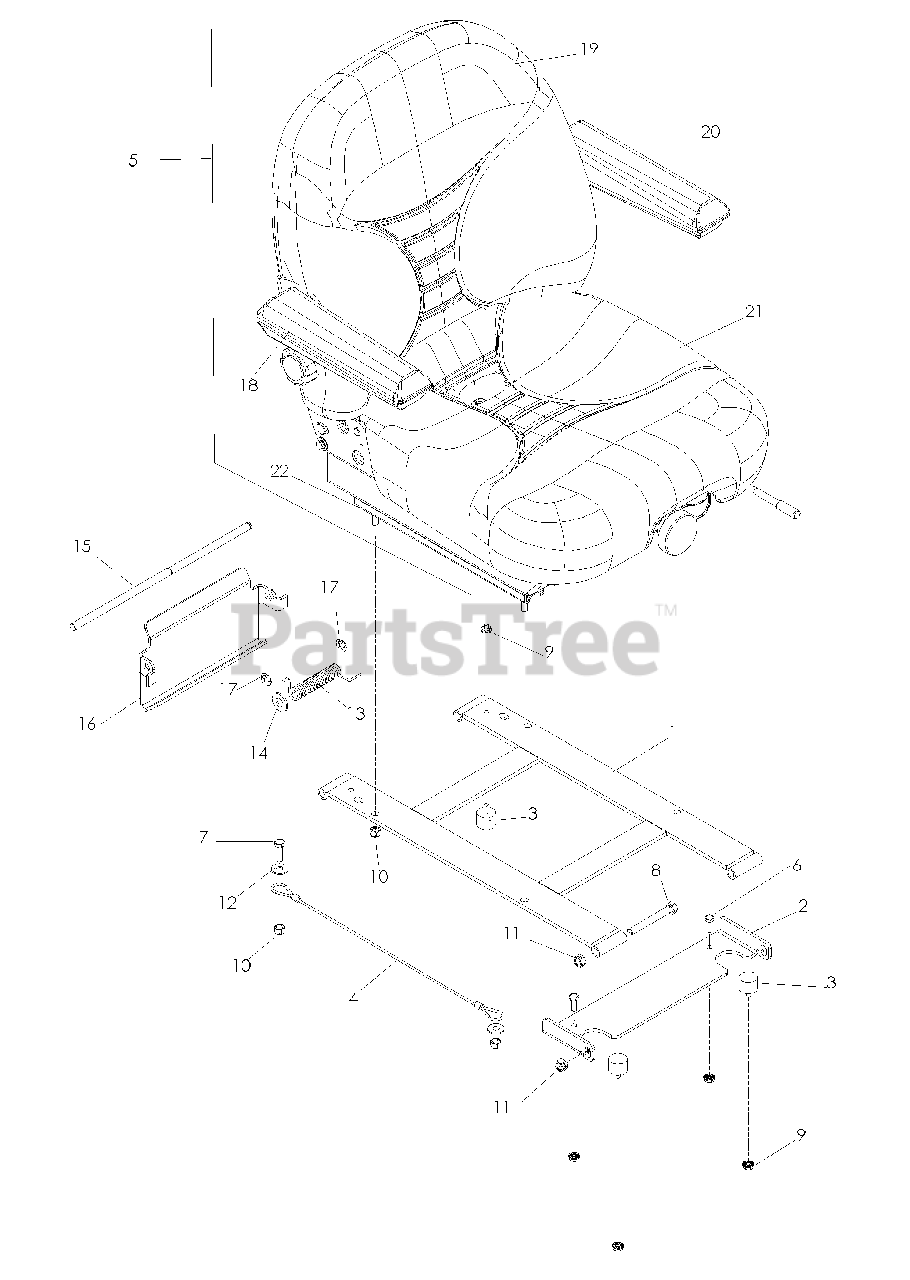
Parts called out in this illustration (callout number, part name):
1	MOUNT, SEAT
2	BRACKET SEAT
3	STUD, PLATE MOUNT
4	LANYARD, SEAT
5	SEAT, SUSPENSION
6	HCS 1/4-20 x 3/4
7	HCS 5/16-18 x 1
8	HCS 3/8-16 x3
9	NUT 1/4-20 WHIZLK
10	NUT 5/16-18 HEX NYLOC
11	NUT 3/8-16 HEX CTRLK
12	WASHER 5/16 STD FLT
13	SPRING, TORSION
14	WASHER 3/8 SAE FLT
17	RETAINING RING
18	ARMREST KIT, RT
19	BACK CUSHION KIT
20	ARMREST KIT, LT
21	SEAT CUSHION KIT
22	SLIDE KIT, SEAT ADJUSTMENT
